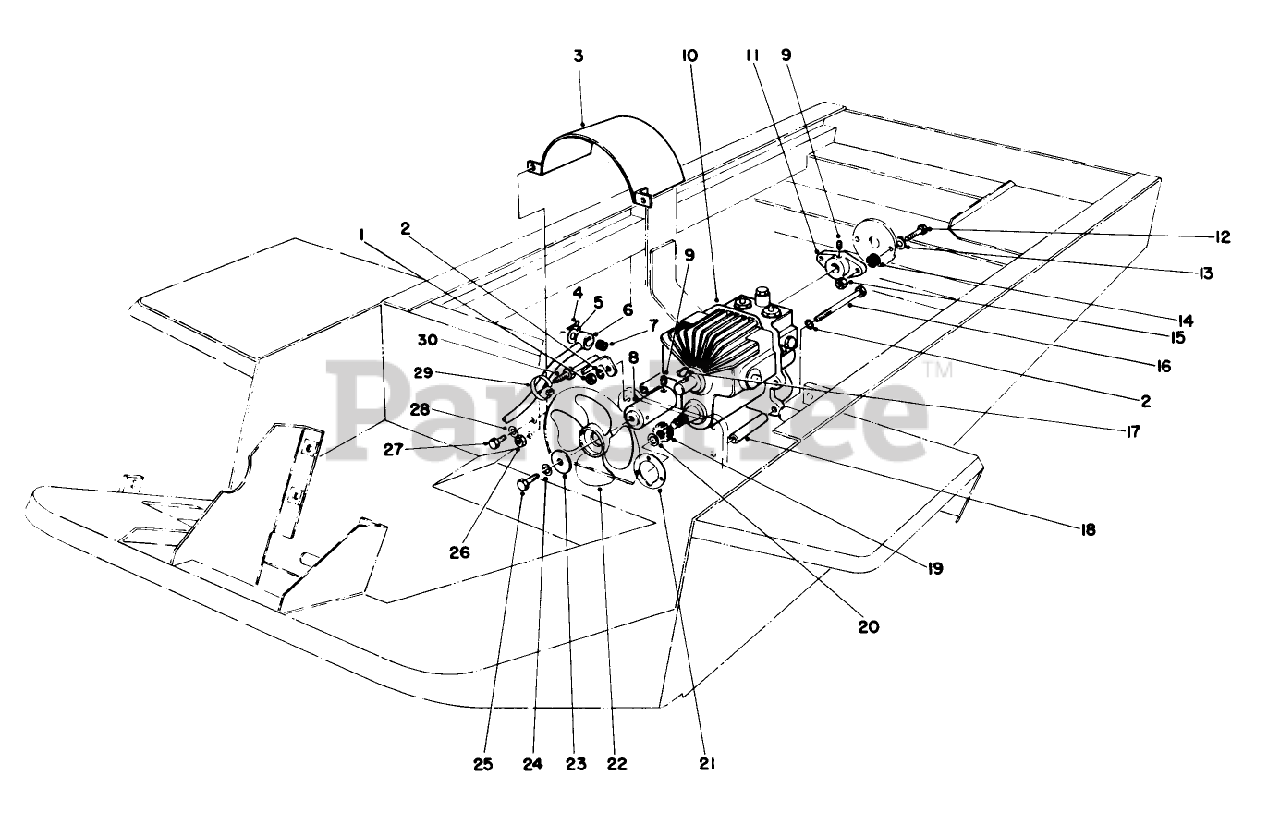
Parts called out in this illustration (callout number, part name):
1	NUT-HEX
2	WASHER-LOCK
3	Fan Shroud
4	PIN-COTTER
5	WASHER-FLAT
6	PUMP CONTROL TUBE WA
7	BUSHING-RUBBER
8	Hub & Plug
9	SCREW-SET, HSH
10	Transmission
11	HUB-PUMP
12	SCREW-HH
13	WASHER-FLAT
14	SPACER-RUBBER COUPLNG
15	NUT-HEX
16	SCREW-HH
17	KEY-WOODRUFF
18	SPACER-MOUNTING
19	Gear
20	Ring-Snap
21	GASKET-TRANSMISSION
23	WASHER
24	WASHER-LOCK
25	SCREW-HH
26	NUT-JAM
27	SCREW-HH
28	WASHER-LOCK
29	TIE-CABLE
30	Axle Support
